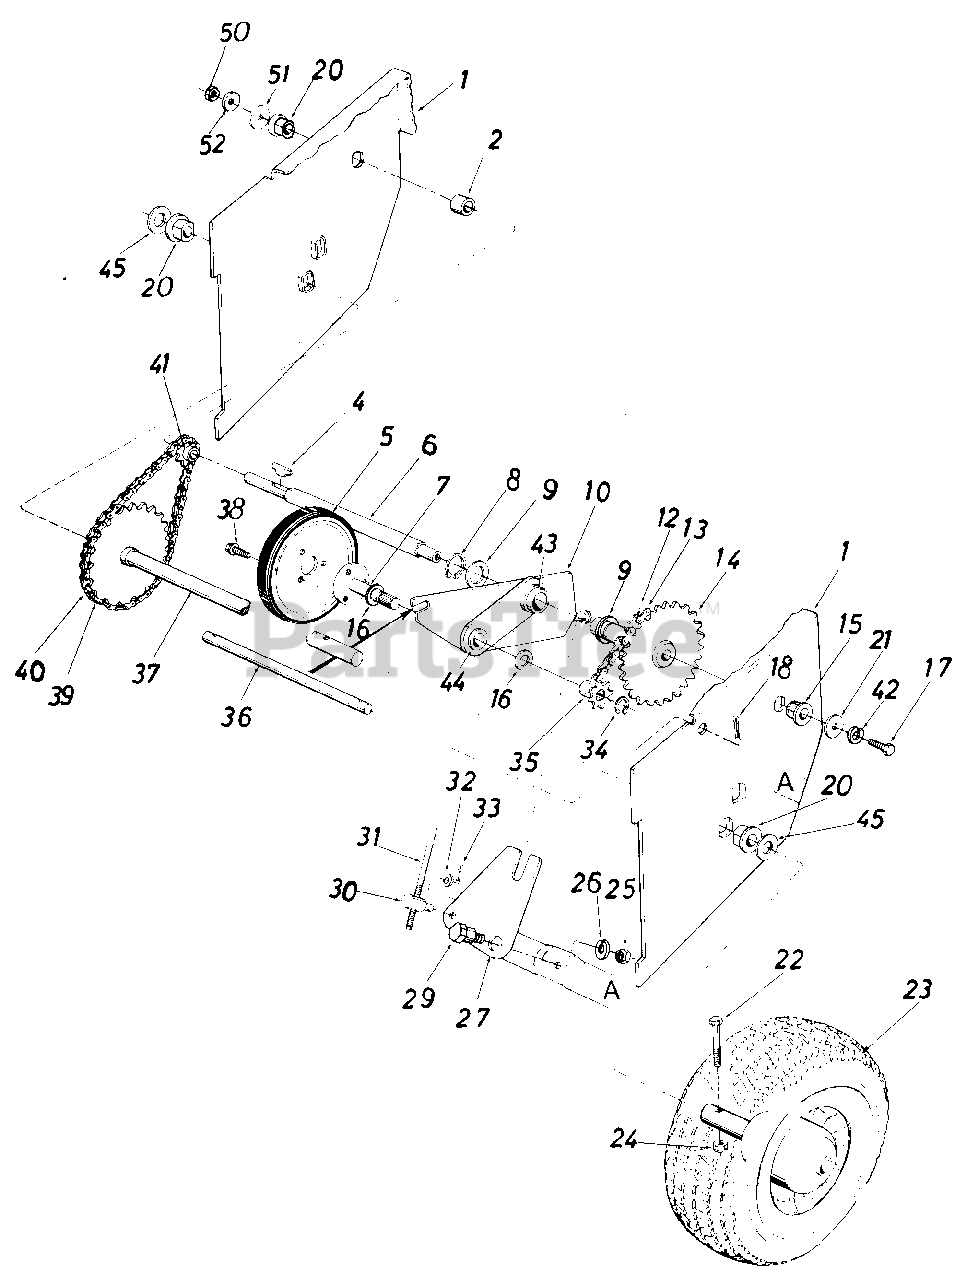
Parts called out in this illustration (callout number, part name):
1	Frame Ass'y.
2	Spacer.50" I.D. x .75" O.D. x.78" Lg.
4	#4 Hi-Pro Key 3/32 x 5/8" Dia.
5	Friction Wheel Ass'y.
6	Hex Shaft
7	Friction Wheel Mounting Plate Ass'y.
8	Snap Ring 1.00" Dia. Shaft
9	Fl-Wash. 1.00" x 1.63" O.D. x .03
10	Sliding Bracket Ass'y.
12	#41 Chain 1/2" Pitch x 35 Links
13	Master Link for #41 Chain
14	32 Teeth Sprocket Ass'y.
15	Hex Flange Brg. .630" I.D.
16	Fl-Wash. .62" I.D. x 1.00" O.D. x .06
17	Hex Lock Bolt 5/16-18 x .62" Lg.
18	Cotter Pin 3/32" Dia. x .75"-Lg.*
20	Flange Brg. w/Flats .755" I.D.
21	Fl-Wash. .34" I.D. x 1.12 O.D. x .125
22	Hex Bolt 5/16-24 x 1.50" Lg.
23	Wheel Ass'y. Comp. (10.5 x 3.5)
24	Hex Ins. Jam L-Nut 5/16-24 Thd.
25	Hex Jam Nut 3/8-16 Thd.
26	L-Wash. 3/8" I.D.*
27	Shifting Linkage Bracket
29	Shld. Bolt .625" Dia. x .170" Lg.
30	Adjustment Ferrule
31	Shifting Rod 5/16" Dia. x 32.50" Lg.
32	Fl-Wash. .34" I.D. x .64" O.D. x .06
33	Cotter Pin 3/32" Dia. x .75" Lg.*
34	Snap Ring .562" Dia. Shaft
35	Sprocket 7 Teeth x .50" Pitch
36	Shaft .50" Dia. x 9.50" Lg.
37	28 Teeth Wheel Axle Ass'y.
38	Hex Wash. Hd. Self-Tap Scr. 5/16-24 x .50" Lg.
39	#41 Chain 1/2" Pitch x 43 Links
40	Master Link for #41 Chain
41	8 Teeth Center Sprocket
42	L-Wash. 5/16" I.D.
43	Bearing
44	Bronze Bearing
45	Fl-Wash. .76" I.D. x 1.49 0 O.D.
50	Hex Ins. L-Nut 1/2-20 Thd.
51	Fl-Wash. .53 I.D. x 1.25 O.D. x .10
52	Bell-Wash. .50 I.D. x 1.0 O.D. x .075
